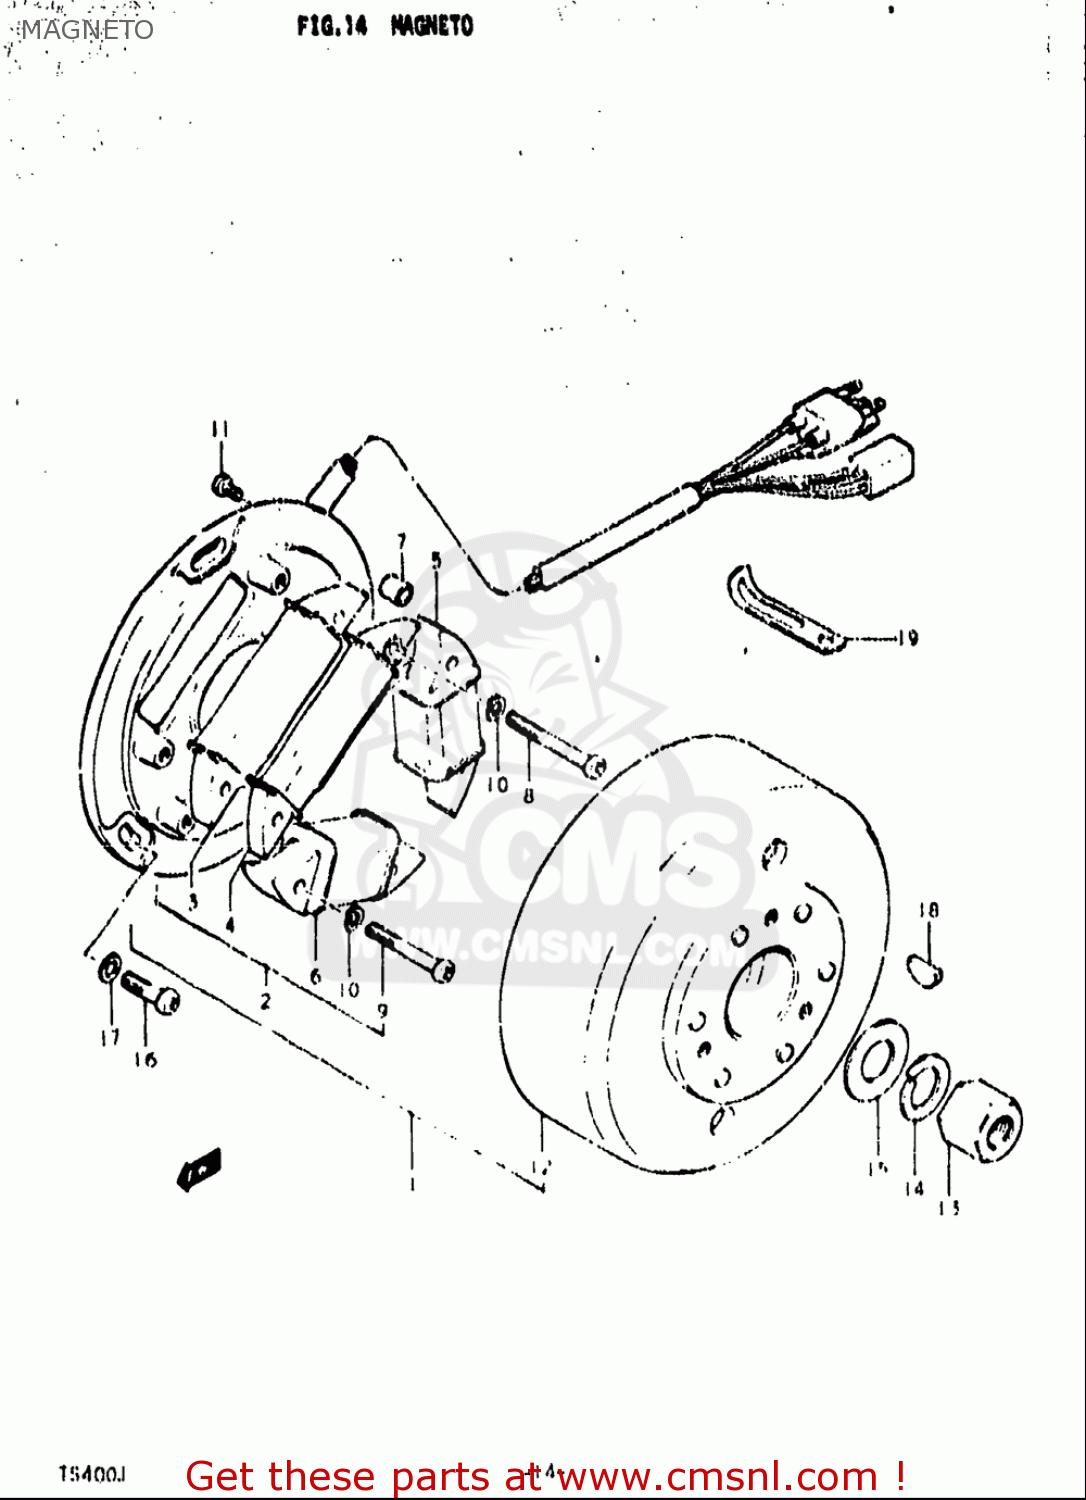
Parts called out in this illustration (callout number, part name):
3	COIL,PRIMARY
4	COIL,PULSER
5	COIL,LIGHTING
8	SCREW
9	SCREW
10	WASHER,LOCK
11	SCREW 4X6
13	NUT
14	WASHER,LOCK
15	WASHER(14X27X3)
16	SCREW
17	WASHER
18	KEY
19	CLAMP(L:65)
